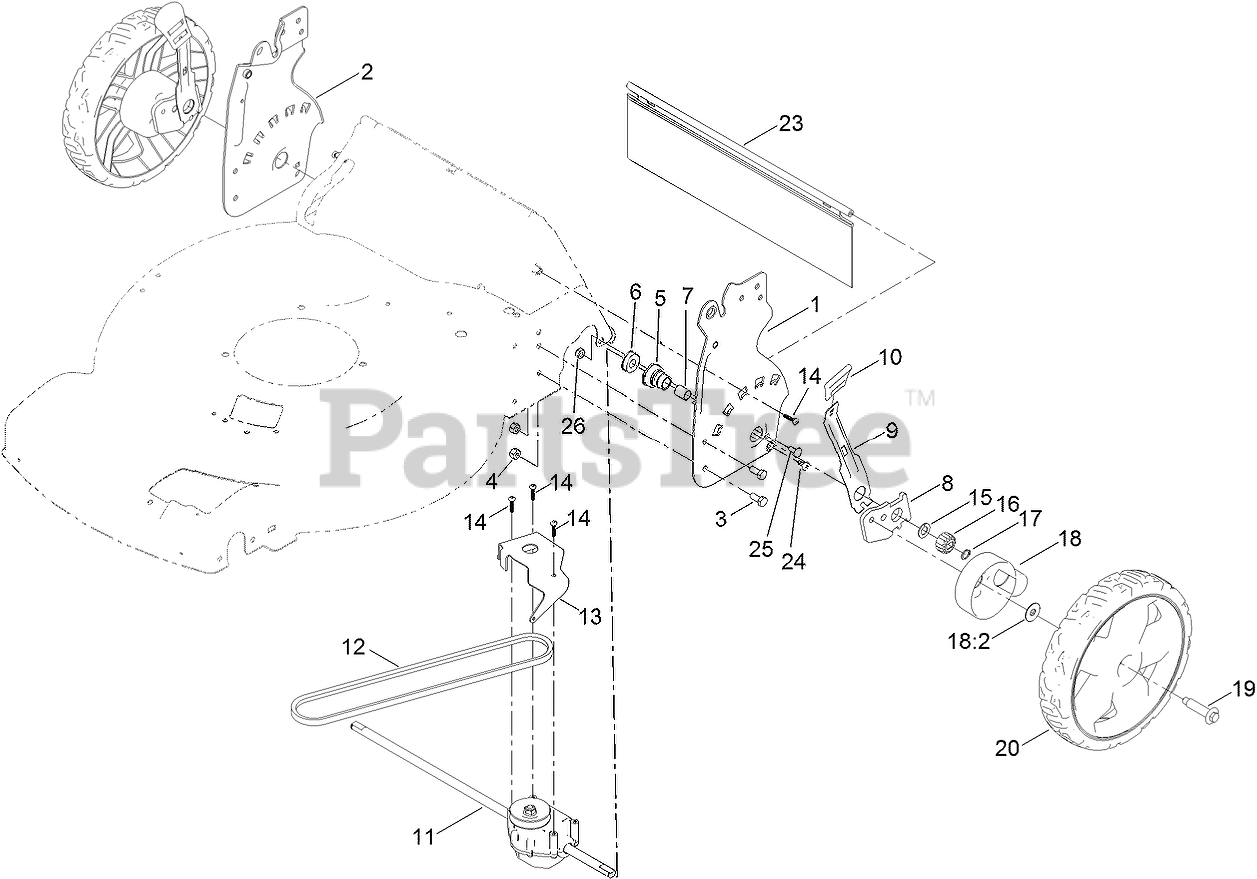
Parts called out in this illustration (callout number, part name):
1	ASM-PLATE, HOC (LH)
2	ASM-PLATE, HOC (RH)
3	SCREW-HH
4	NUT-LOCK, NI
5	RETAINER-BUSHING, HOC
6	BEARING-BALL
7	BUSHING-SLEEVE
8	ARM-PIVOT, REAR
9	ARM-SPRING
10	KNOB-HOC
11	TRANSMISSION-RWD (6:1)
12	BELT-V
13	BRACKET-TRANSMISSION
14	SCREW-PLASTITE
15	WASHER-THRUST
16	GEAR-PINION, 15T
17	RING-RETAINING
18	GEAR COVER ASM
18:2	WASHER-STEPPED
19	BOLT-SHOULDER
20	WHEEL GEAR ASM
23	SHIELD-TRAILING
24	SCREW-PTH
25	BOLT-CARR
26	NUT-LOCK, NI
